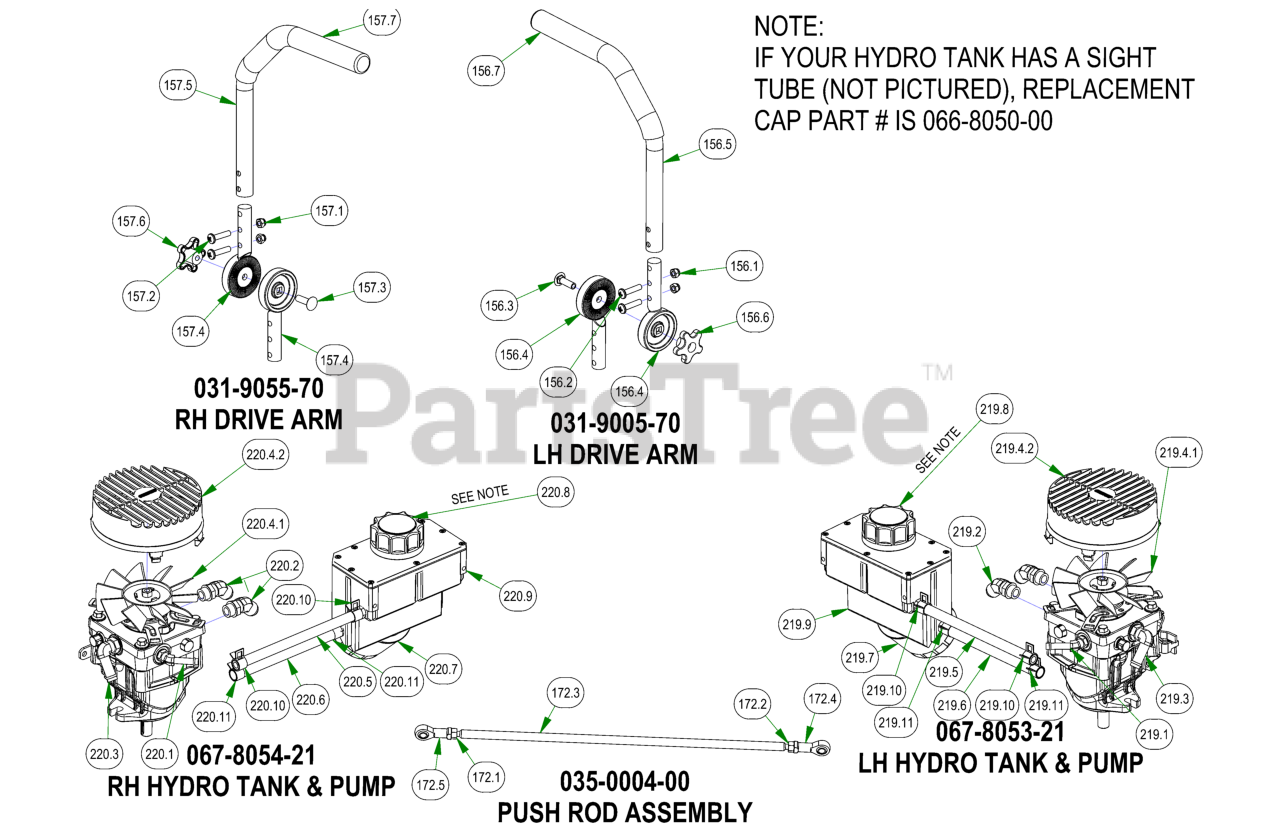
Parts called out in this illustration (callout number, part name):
156	2019 Left Hand ADJ. Steering Arm Kit
156.1	5/16-18 NYL INS L/N ZC
156.2	5/16-18 x 1 3/8" Futton Head Torx Drive Bolt
156.3	3/8-16 X 1-1/4 CARRIAGE BOLT ZINC
156.4	2019 Steering Arm Adjuster Casting
156.5	2019 Steering Arm Tube
156.6	Black Knob for Adjustable Steering Arm
156.7	Black Steering Arm Grip
157	2019 Right Hand ADJ. Steering Arm Kit
157.1	5/16-18 NYL INS L/N ZC
157.2	5/16-18 x 1 3/8" Futton Head Torx Drive Bolt
157.3	3/8-16 X 1-1/4 CARRIAGE BOLT ZINC
157.4	2019 Steering Arm Adjuster Casting
157.5	2019 Steering Arm Tube
157.6	Black Knob for Adjustable Steering Arm
157.7	Black Steering Arm Grip
172	2019 Outlaw Gen2 XP Push Rod Assembly
172.1	5/16" RH Fine Threaded Jam Nut
172.2	5/16" LH Fine Threaded Jam Nut
172.3	2019 Outlaw Gen2 Xp Rod
172.4	Spherical Rod End - Outlaw
172.5	Spherical Rod End - Outlaw
219	2021 LH ROGUE HYDRO TANK LINE ASSY
219.1	ZT Fitting, 3/8 x 3/8 45 Degree, 4603-6-6
219.2	2019 Outlaw 45 Degree Pump Fitting #6802-10-08
219.3	90 Degree Fitting, 1/2 x 3/4, 4601-8-8
219.4	2019 Rogue/Renegade Left Pump 16cc
219.4.1	Hydro Fan - Light/Pup/Outlaw XP
219.4.2	Fan Guard 6" - Fits Wheel
219.5	3/8" Clear Hose x 4 1/2"
219.6	1/2 Clear Braded Hose Priced/Foot x 9.5"
219.7	Hydraulic Filter
219.8	Hydraulic Tank Cap W/Dipstick
219.9	2019 Left Outlaw Gen2 Hydro Tank Suspension Only
219.10	3/8" Hose Clamp
219.11	1/2 Hose Clamp
220	2021 RH ROGUE HYDRO TANK LINE ASSY
220.1	ZT Fitting, 3/8 x 3/8 45 Degree, 4603-6-6
220.2	2019 Outlaw 45 Degree Pump Fitting #6802-10-08
220.3	90 Degree Fitting, 1/2 x 3/4, 4601-8-8
220.4	2019 Rogue Right Pump 16cc
220.4.1	Hydro Fan - Light/Pup/Outlaw XP
220.4.2	Fan Guard 6" - Fits Wheel
220.5	3/8" Clear Hose x 4 1/2"
220.6	1/2 Clear Braded Hose Priced/Foot x 9.5"
220.7	Hydraulic Filter
220.8	Hydraulic Tank Cap W/Dipstick
220.9	2019 Right Outlaw Gen2 Hydro Tank Suspension Only
220.10	3/8" Hose Clamp
220.11	1/2 Hose Clamp
